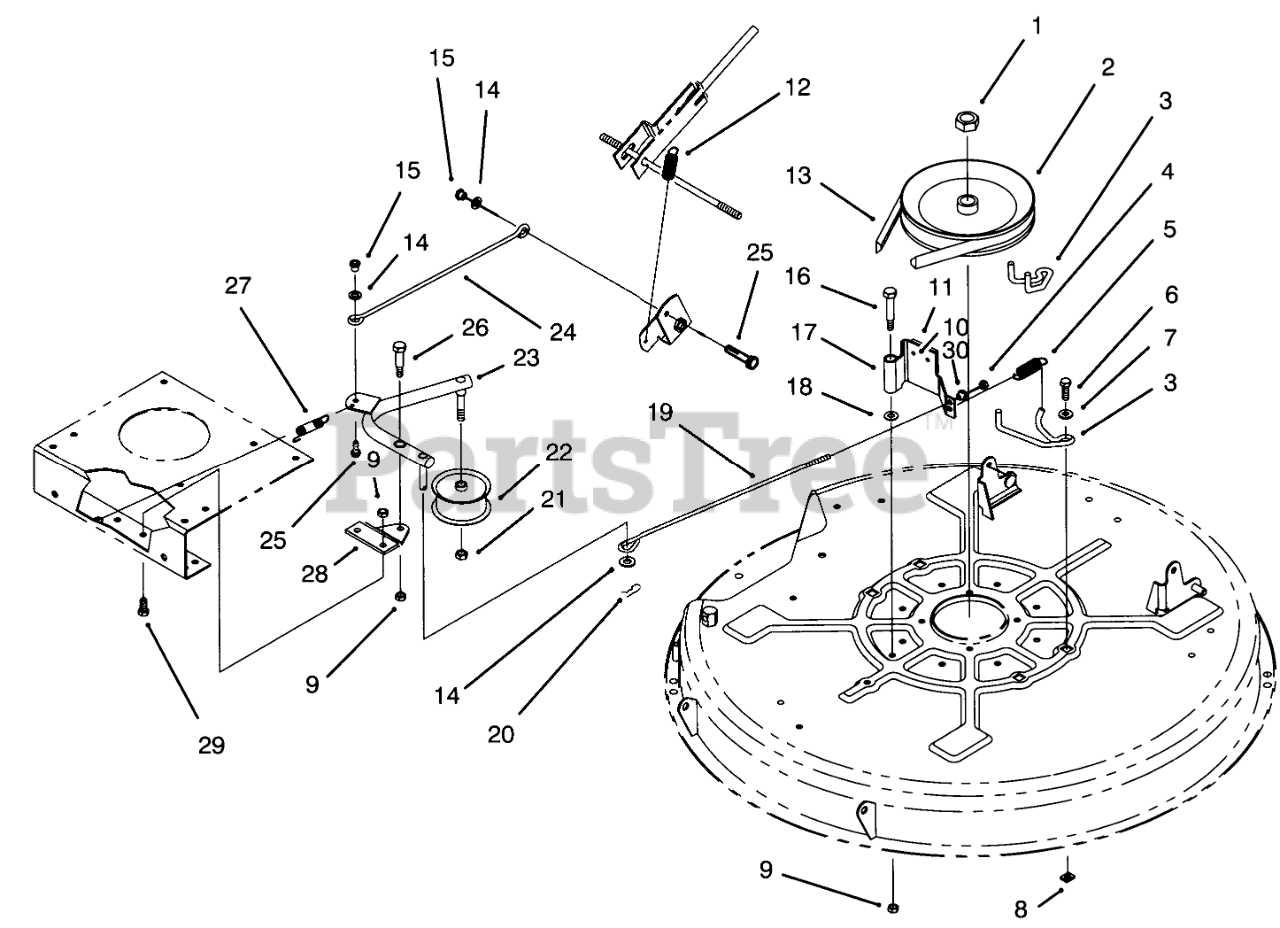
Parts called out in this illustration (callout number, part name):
1	NUT-HEX
2	PULLEY-DECK
3	GUIDE-BELT, DECK
4	NUT-LOCK, NI
5	SPRING-EXTENSION
6	SCREW-HH
7	WASHER-PIVOT
8	NUT-RETAINER
9	NUT-LOCK, NI
10	RIVET-BLIND
11	PAD-BRAKE
12	CABLE SPRING ASM
13	V-BELT
14	WASHER-FLAT
15	POST-MOUNTING, LINKAGE
16	BOLT-SHOULDER
17	Deck Brake Assembly (Incl. Ref. #10. & .11)
18	WASHER-PLAIN
19	ROD-BRAKE, DECK
20	PIN-COTTER
21	NUT-LOCK, NI
22	PULLEY-IDLER
23	Arm-Idler
24	ROD-ENGAGE, DECK
25	SCREW-HHF
26	SCREW-SHOULDER, HH
27	SPRING-RETURN, BRAKE
28	Plate-Idler Mount
29	SCREW-HH
30	BALL-SWIVEL, STOP
